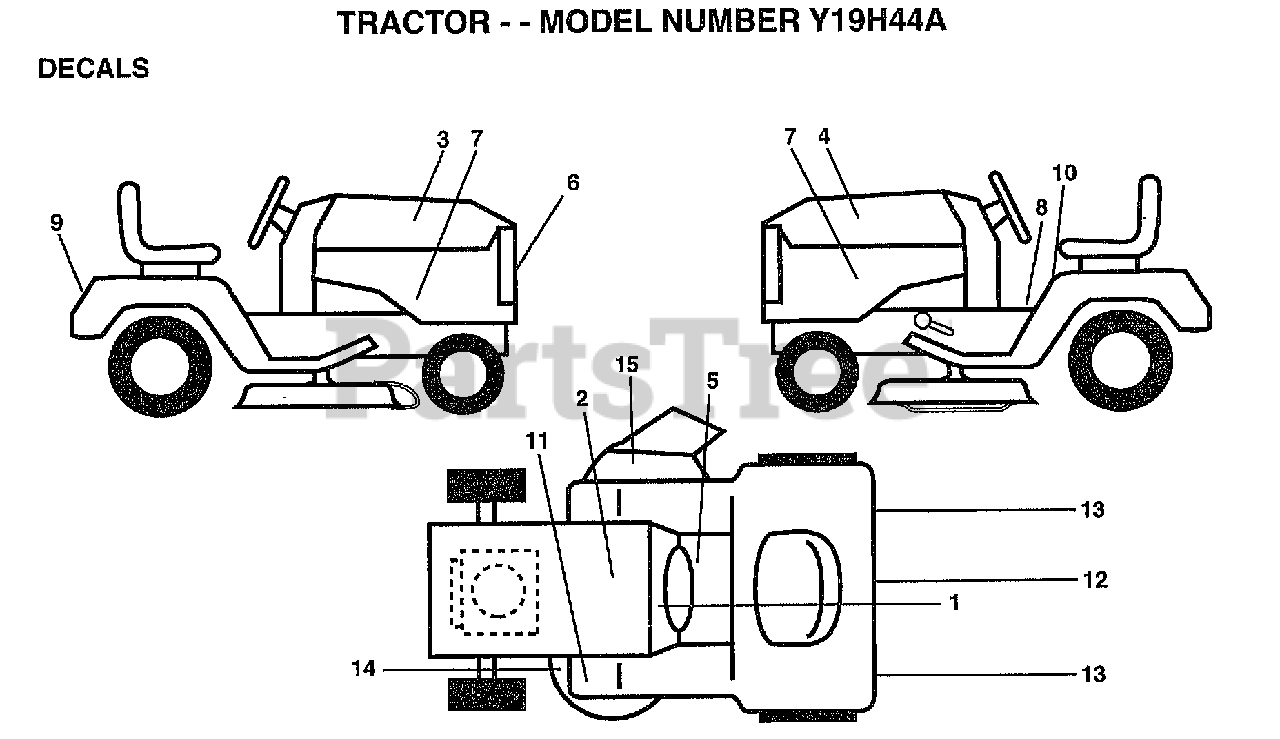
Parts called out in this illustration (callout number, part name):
1	DECAL.DASH.INSTR.
2	DECAL
4	DECAL HOOD LH
5	DECAL BRAK PARK
6	DECAL.GRILL.YARDP
7	DECAL.PNL.SIDE.19
8	DECAL SADL HYDRO
10	DECAL CAUTION
11	DECAL T
12	DECAL D-BAR CNTRL
13	REFLECTOR-TAIL YT
14	"DECAL.V.BELT.44"""
15	"DECAL, WARNING"
